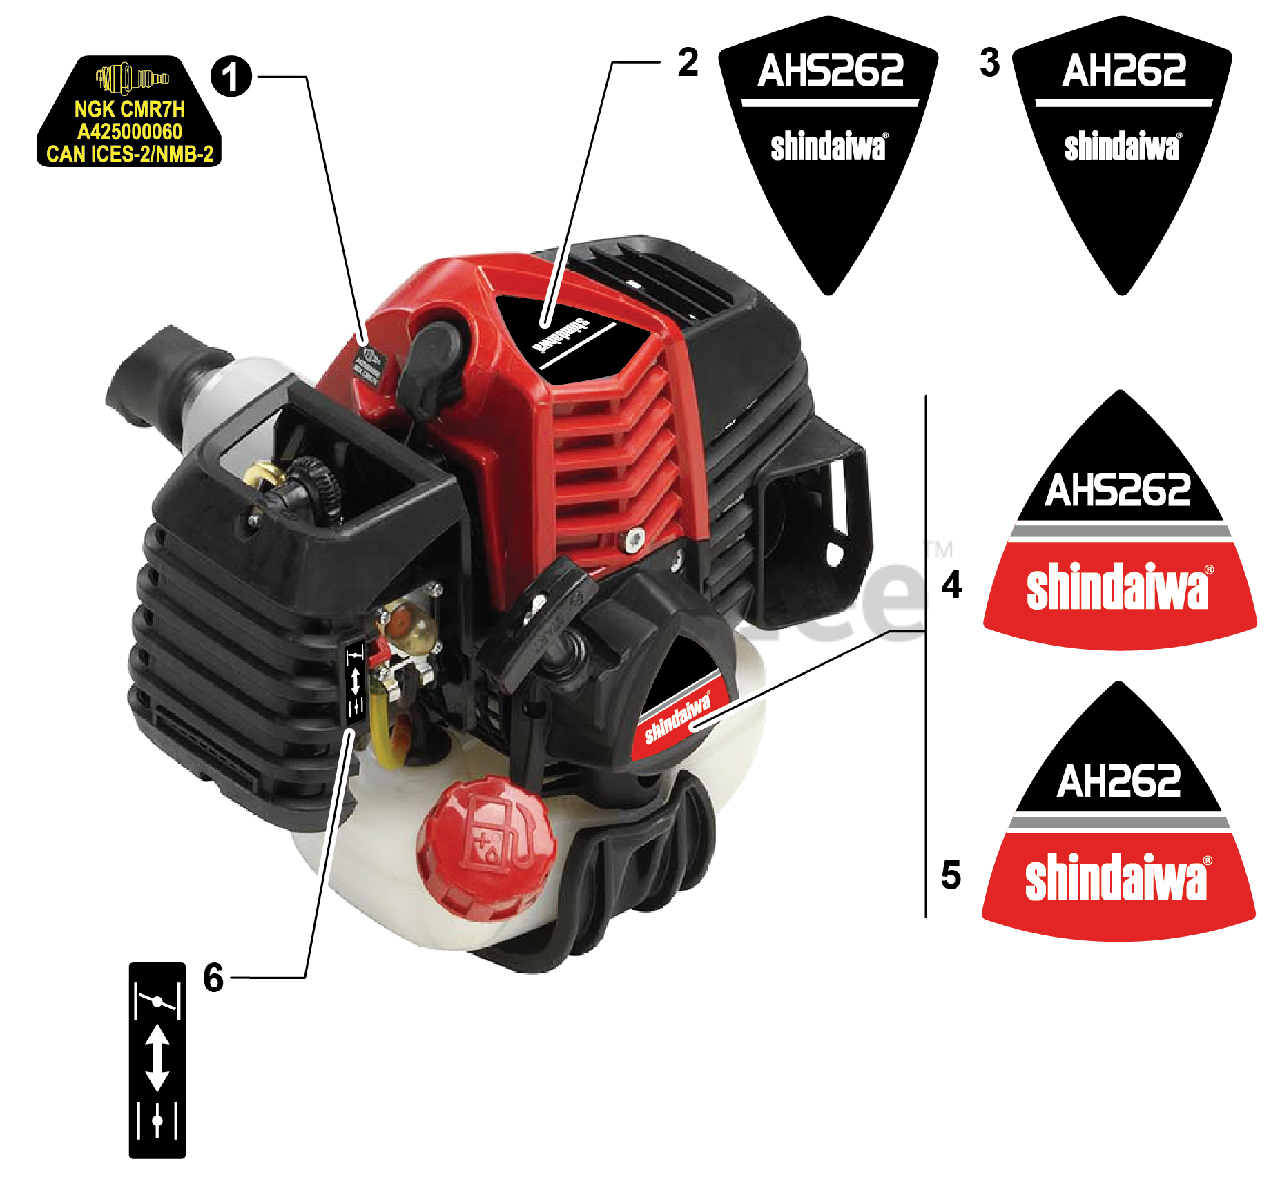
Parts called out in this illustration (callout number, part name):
1	LABEL, SPARK PLUG - CMR7H
2	LABEL - MODEL AHS262
3	LABEL - MODEL AH262
4	LABEL, RECOIL STARTER - AHS262
5	LABEL, RECOIL STARTER - AH262
6	LABEL, CHOKE
